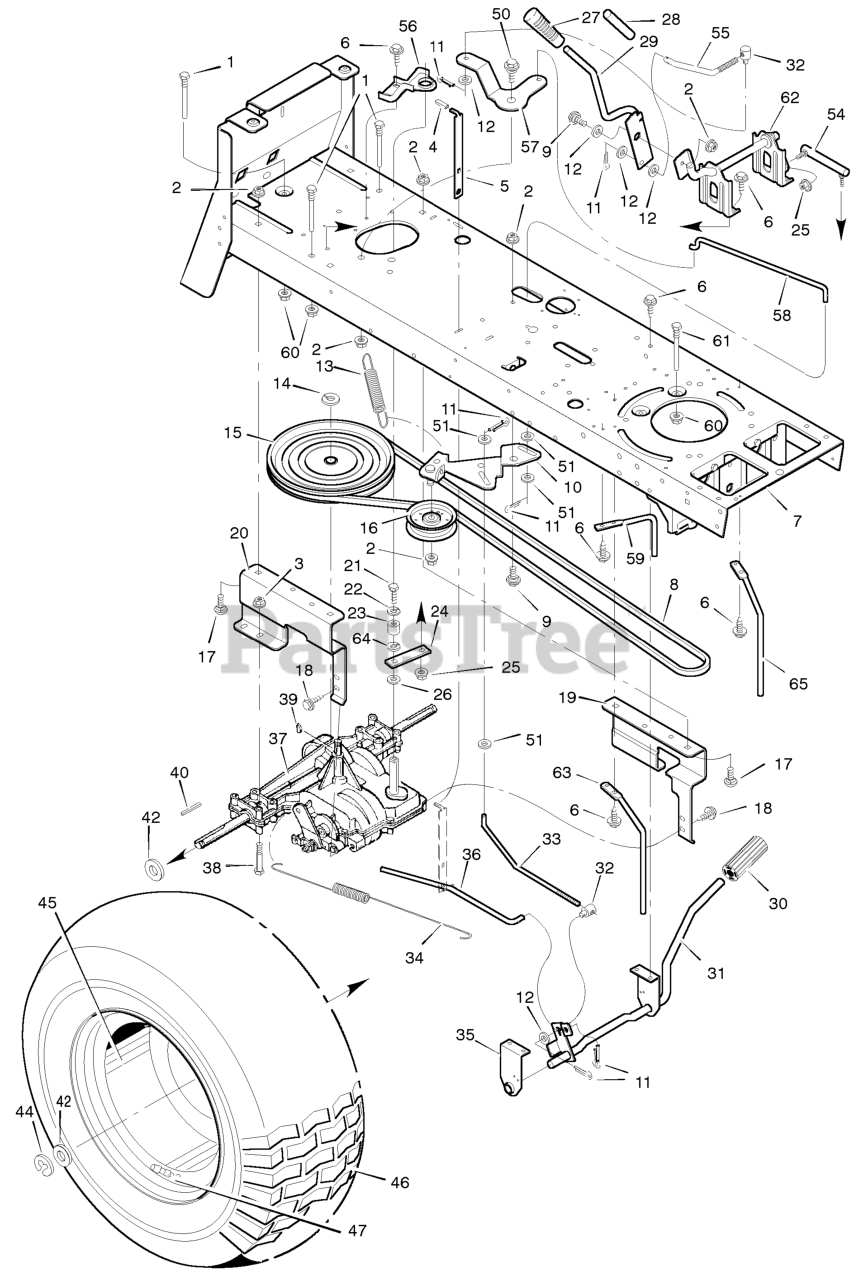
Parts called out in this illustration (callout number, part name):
1	Guide, Belt
2	Locknut, Flange
3	Locknut, Flange
5	Lever, Parking Brake
8	Belt, Motion Drive
9	Bolt, Shoulder
10	Bracket Assembly, Idler
11	Pin, Cotter
12	Washer
13	Spring, Drive Extension
14	Ring, Retainer
15	Pulley, Motion Drive
16	Pulley, Backside Idler
17	Bolt, Carriage
19	Bracket, Left Transaxle
20	Bracket, Right Transaxle
21	Bolt, Hex
22	Lockwasher
23	Pilot, Support
24	Yoke, Shift Lever
25	Locknut
28	Grip, Inner
29	Lever, Shift
30	Pedal, Clutch/Brake
31	Lever Assembly, Pedal
32	Nut, Adjustable
33	Rod, Clutch
34	Spring, Brake Extension
35	Bracket, Pedal Support
36	Rod, Brake Latch
37	Transaxle, Peerless **
38	Bolt, Hex
39	Key, Woodruff No. 9
40	Key, Square
42	WASHER, 1-1.3 16G FLT
45	Wheel & Tire Assembly
46	Tire Only *
47	Valve Stem
50	Bolt, Shoulder
51	Washer
52	Washer
54	Link, Shifter
55	Link, Clutch
56	Bracket, Support
57	Bracket, Pivot
58	Rod, Clutch
59	Guide, Belt
60	Nut, Flange
61	Guide, Belt
62	Shifter Assembly
63	Guide, Belt
65	Guide, Belt
